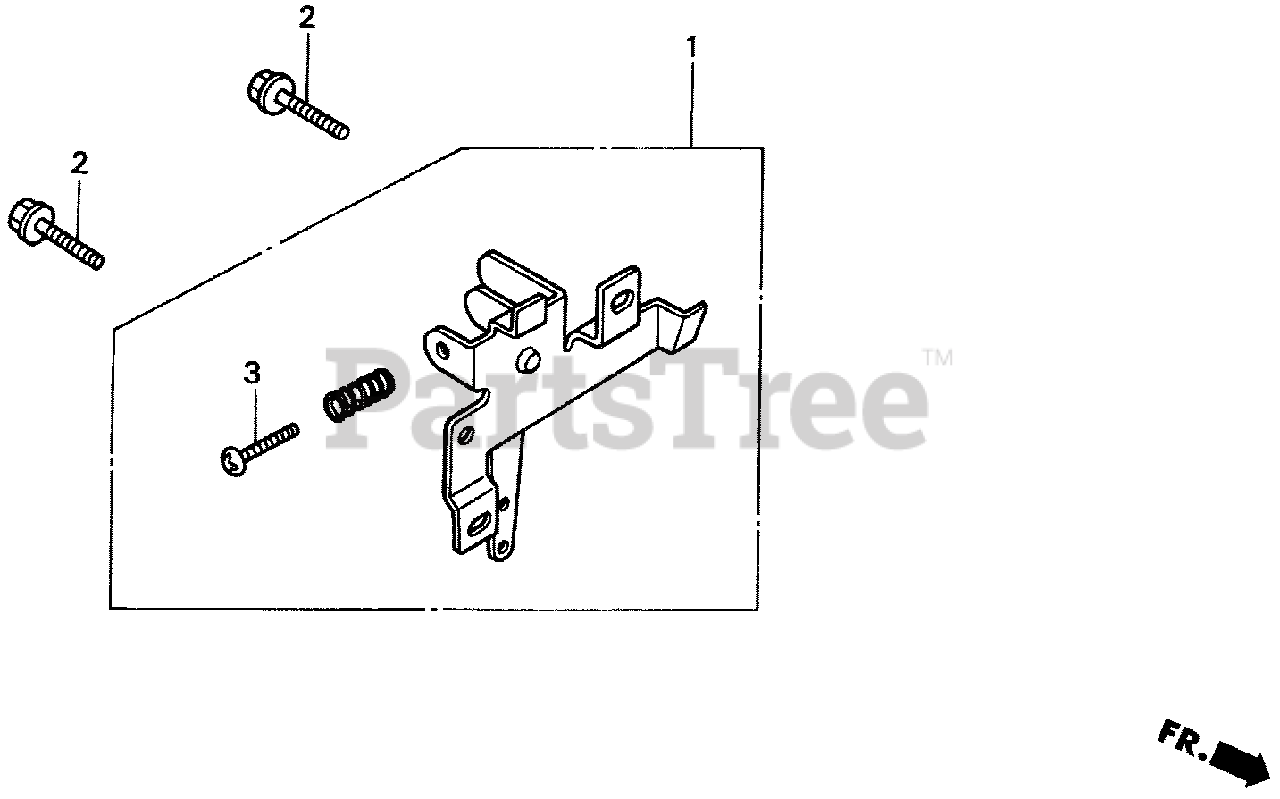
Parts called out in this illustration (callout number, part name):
1	ADJUSTER ASSY., THROTTLE
2	BOLT, FLANGE (5X10)
3	SCREW, PAN (4X14)
